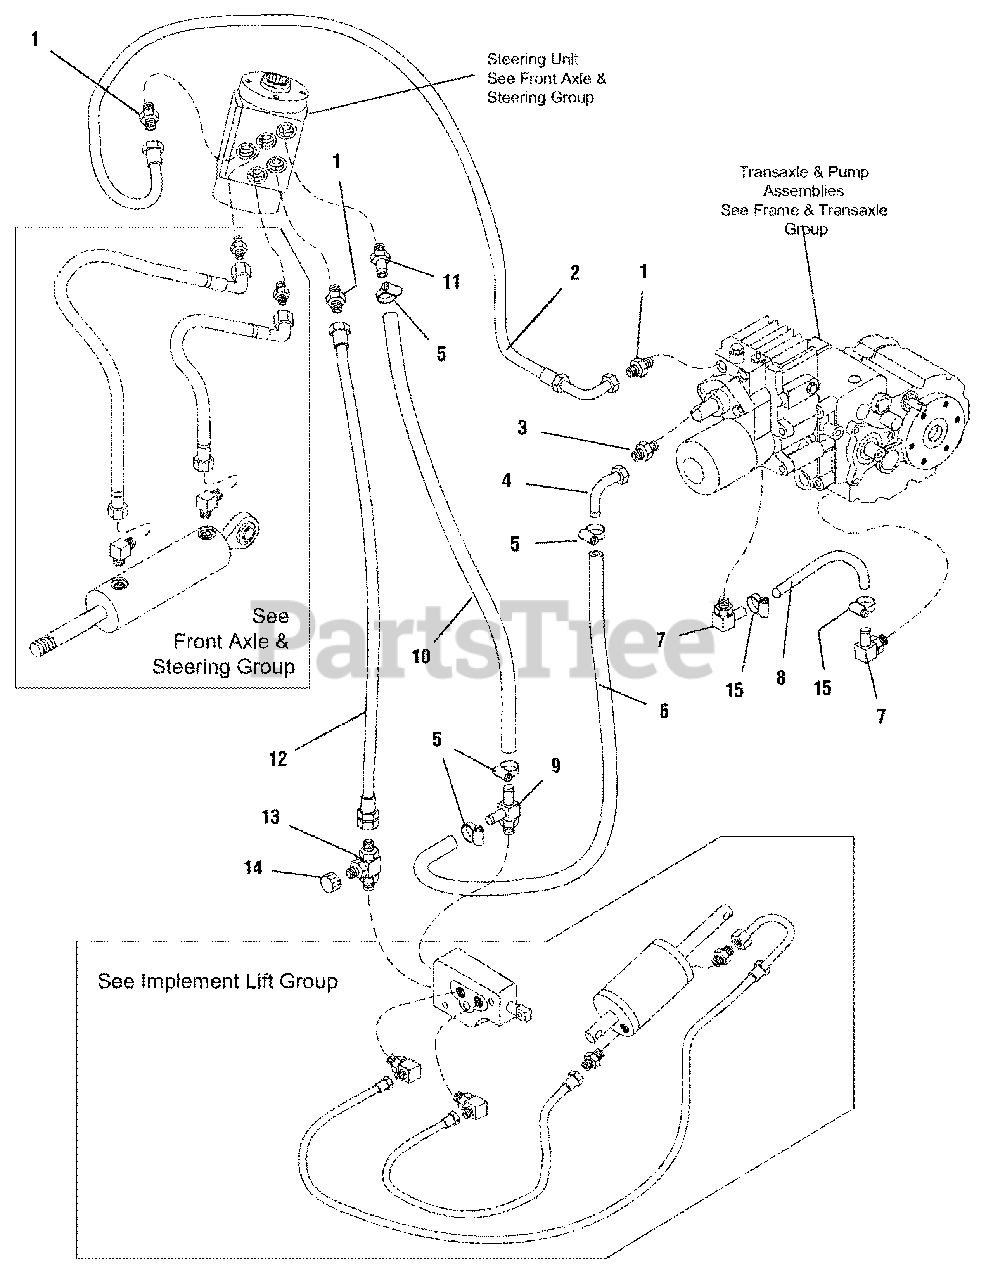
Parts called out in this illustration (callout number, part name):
1	FITTING, Male, Straight
2	HOSE, Pump to Steer
3	FITTING, Hydraulic
5	CLAMP, Hose
6	HOSE, Return
7	FITTING, Hydraulic, 7/8-14
8	HOSE, Pre Formed
9	FITTING, Tube
10	HOSE ASSEMBLY, Return (Steer/Lift)
12	HOSE ASSEMBLY, Steer to Lift
13	FITTING, Tube Tee
15	CLAMP, Hose
